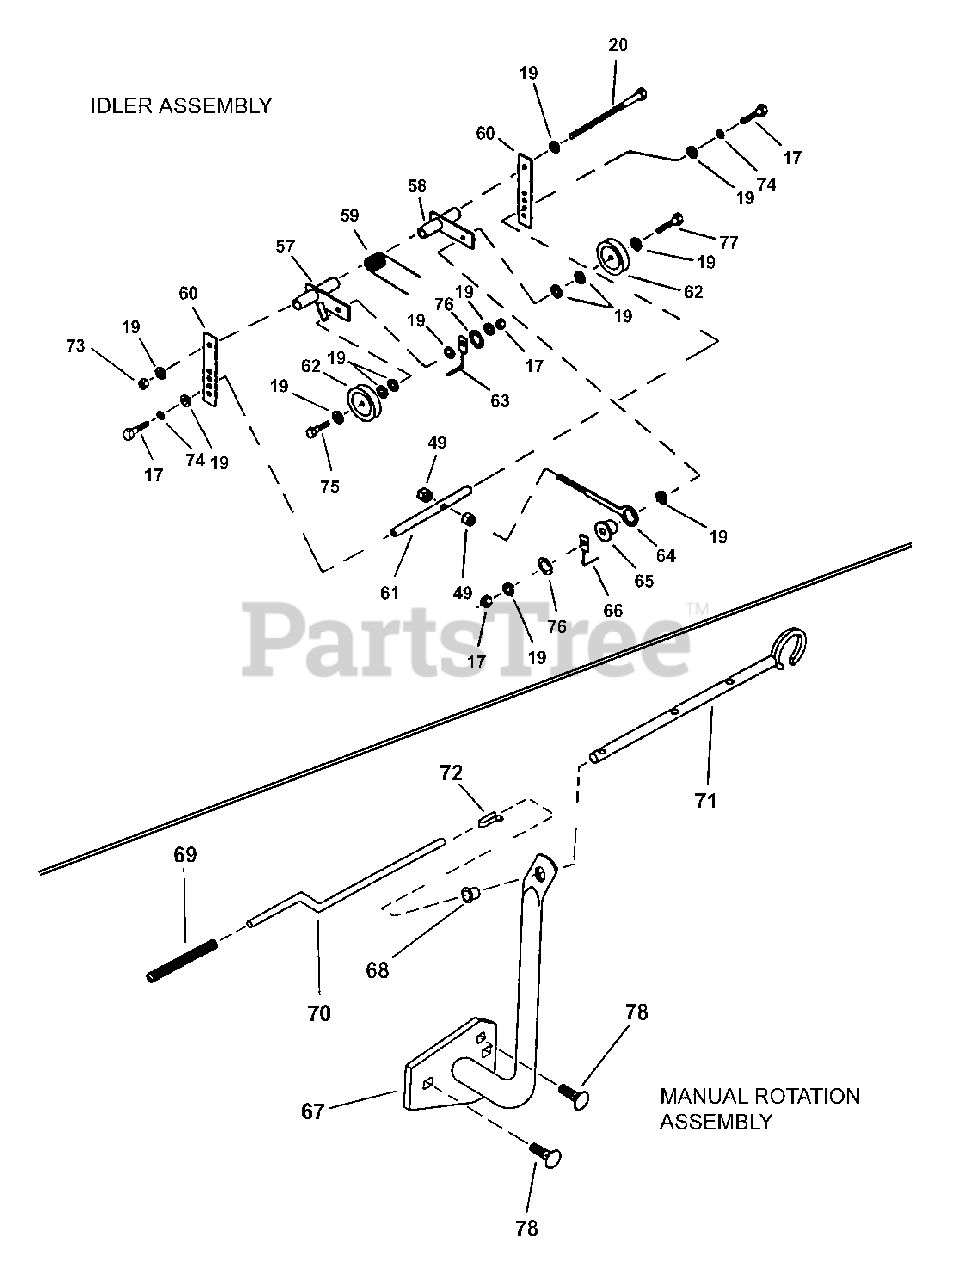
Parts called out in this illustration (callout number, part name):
17	BOLT, 3/8-16 x 1-1/4" Hex
19	WASHER, 7/16" Flat
20	BOLT, 3/8-16 x 8-1/2" Hex Head
49	NUT, 5/16-18 Hex Nyloc
57	BRACKET, Left Idler (weldment)
58	BRACKET, Right Idler (weldment)
60	BRACKET, Adjusting
61	ROD, Adjusting
62	IDLER PULLEY
63	BELT GUIDE (short bend)
64	EYE BOLT, 5/16-18
65	SPACER, Idler
66	BELT GUIDE (long bend)
67	SUPPORT, Rotation Handle (weldment)
68	GROMMET
69	GRIP, Handle
70	HANDLE, Rotation
71	TUBE, Handle
72	BUTTON, Snap
73	NUT, 3/8-16 Hex Nyloc
74	WASHER, 3/8" Lock
75	BOLT, 3/8-16 x 2-1/4" Hex
76	WASHER, 3/8" Internal Tooth Lock
77	BOLT, 3/8-16 x 2-3/4" Hex
78	BOLT, 3/8-16 x 1-1/4" Square Neck Carriage
